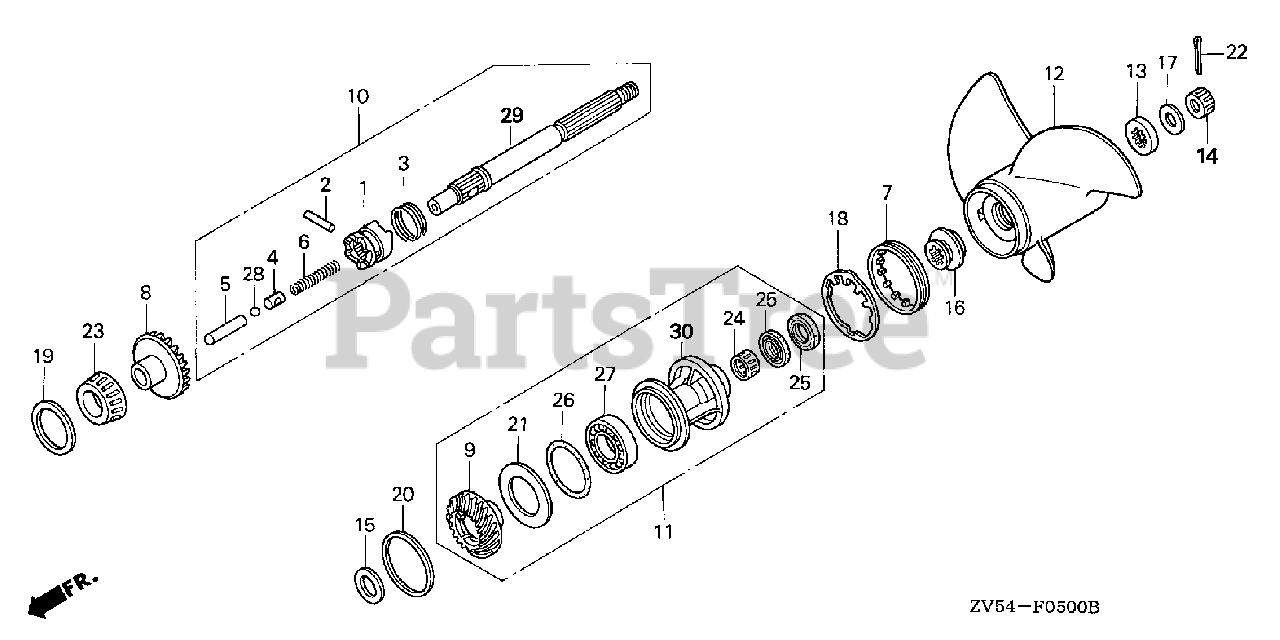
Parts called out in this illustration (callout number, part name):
1	SHIFTER, CLUTCH
2	PIN, SHIFTER (6.3X33)
3	RING, CROSS PIN
4	HOLDER, SHIFTER PIN
5	SLIDER, SHIFT
6	SPRING, SHIFT
7	NUT, GEAR CASE END
8	GEAR, FR. BEVEL
9	GEAR, RR. BEVEL
10	SHAFT ASSY., PROPELLER
11	HOLDER ASSY., PROPELLER SHAFT
12	PROPELLER, THREE-BLADE (11-1/4X13) *NH283* (STIN GRAY)
12	PROPELLER, THREE-BLADE (11-1/2X12) *NH283* (STIN GRAY)
12	PROPELLER, THREE-BLADE (11-3/4X10) *NH283* (STIN GRAY)
12	PROPELLER, THREE-BLADE (11-1/2X14-1/4) *NH283* (STIN GRAY)
13	SPACER (10MM)
14	NUT, CASTLE (16MM)
15	WASHER (22MM)
16	WASHER, PROPELLER THRUST
17	WASHER (17MM)
18	WASHER, CLAW
19	SHIM, FR. BEVEL (51X57X0.10) (A)
19	SHIM, FR. BEVEL (51X57X0.15) (B)
19	SHIM, FR. BEVEL (51X57X0.30) (C)
19	SHIM, FR. BEVEL (51X57X0.50) (D)
20	SHIM, RR. BEVEL (73X77X0.10) (A)
20	SHIM, RR. BEVEL (73X77X0.15) (B)
20	SHIM, RR. BEVEL (73X77X0.30) (C)
20	SHIM, RR. BEVEL (73X77X0.50) (D)
21	WASHER, PLAIN (54MM)
22	PIN, COTTER (4.0)
23	BEARING (32X58X17)
24	BEARING, NEEDLE (22X28X20)
25	SEAL, WATER (22X35X7)
26	O-RING (66X5.7)
27	BEARING, RADIAL BALL (6007)
28	BALL, STEEL (#11) (11/32)
29	SHAFT, PROPELLER
30	HOLDER, PROPELLER SHAFT
